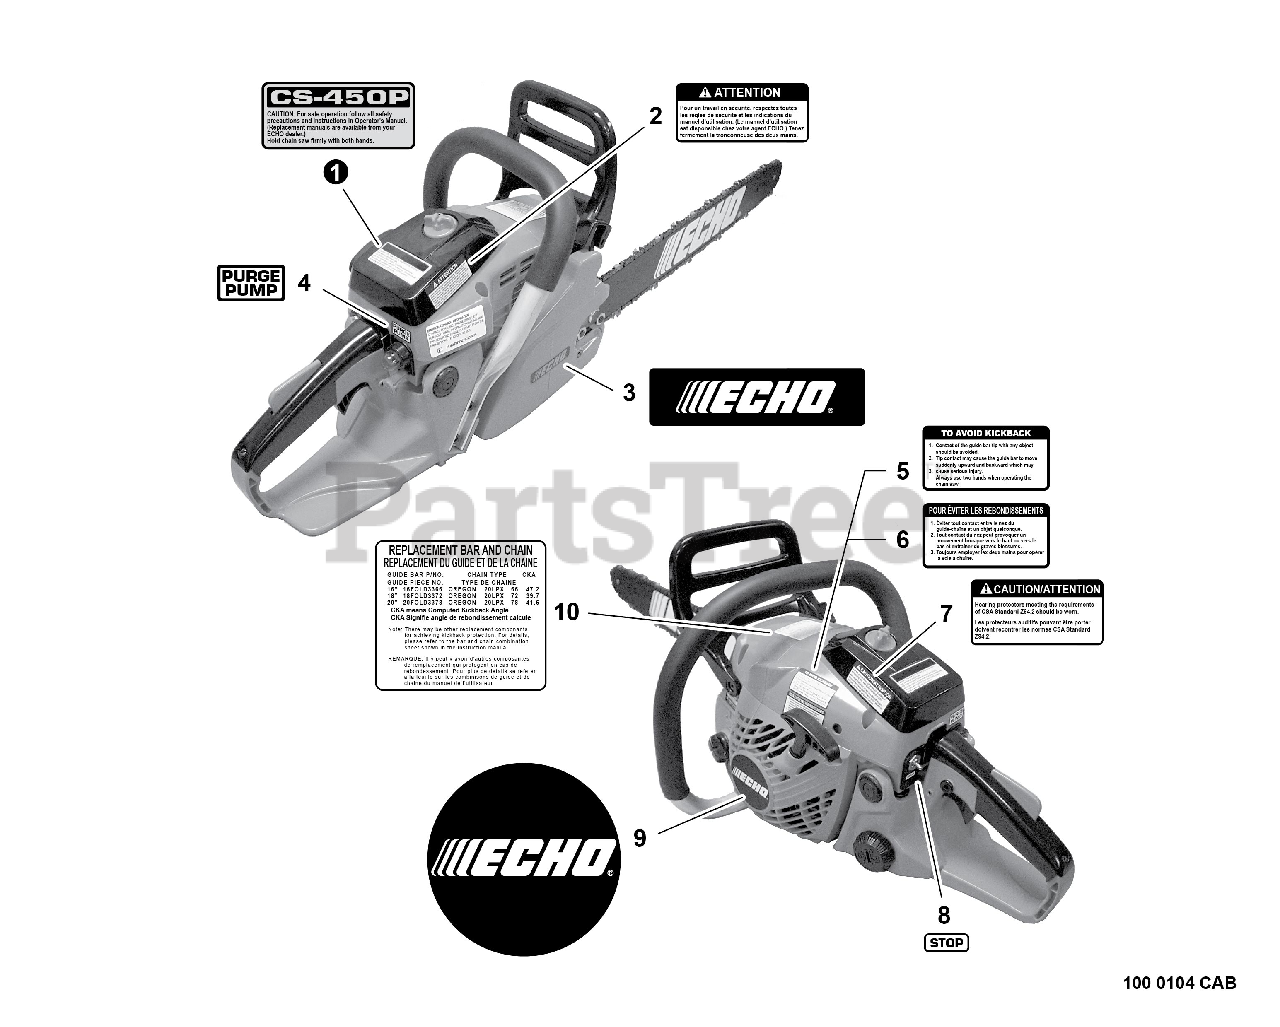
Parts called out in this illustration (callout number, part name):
1	LABEL - MODEL CS-450P
2	LABEL - ATTENTION
3	LABEL - ECHO
4	LABEL - PURGE PUMP
5	LABEL - KICK BACK
6	LABEL - KICK BACK
7	LABEL - NOISE
8	LABEL - STOP
9	LABEL - ECHO
10	LABEL - BAR & CHAIN
